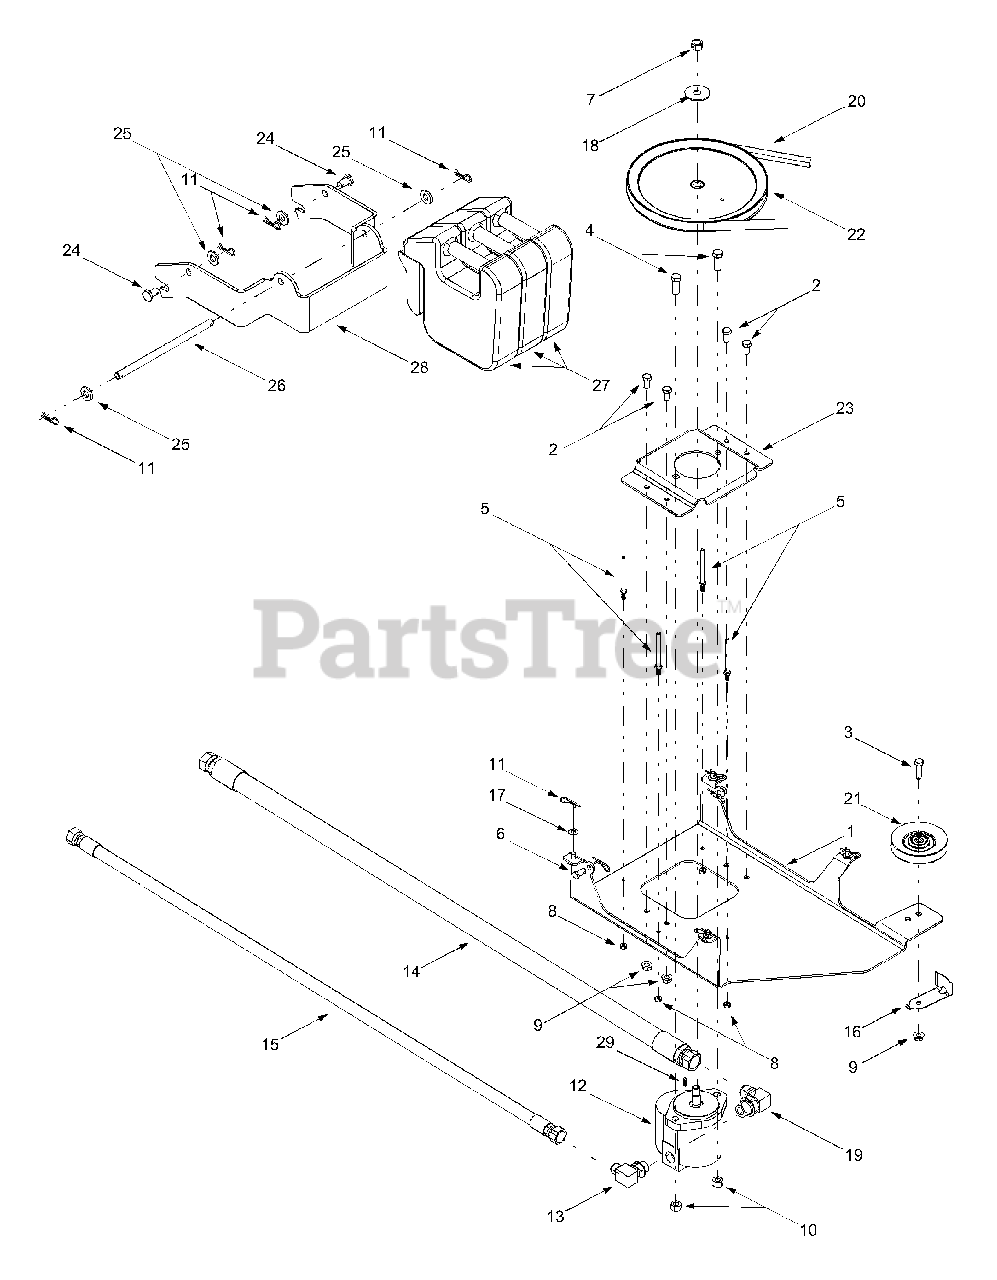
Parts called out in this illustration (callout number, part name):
1	Hydraulic Pump Bracket Assembly
2	Hex Cap Screw, 3/8-16 x.75
3	Hex Cap Screw, 3/8-16 x 1.25
4	Hex Cap Screw, 7/16-20
5	Belt Keeper Pin
6	Clevis Pin, 3/8 x .75
7	Hex Lock Nut, 1/2-20
8	Hex Lock Nut, 1/4-20
9	Hex Lock Nut, 3/8-16
10	Hex Lock Nut, 7/16-20
11	Click Pin, .092 x 1.64
12	Eaton Hydraulic Pump (Includes Ref. 29)
13	90 degree Hydraulic Adapter, 7/8
14	Hydraulic Hose, 1.0625-12 x 54
15	Hydraulic Hose, .875-14 x 49
16	Belt Guard
17	Flat Washer, .344 x .688
18	Flat Washer, .531 x 1.75
19	90 degree Hydraulic Adapter
20	V-belt
21	Idler Pulley, 5/8 x 4.0
22	Drive Pulley, 10.0
23	Pump Mounting Bracket
24	Clevis Pin, .5 x .78
25	Flat Washer, .531 x 1.062
26	Weight Guard Rod
27	45 lb. Suitcase Weight
